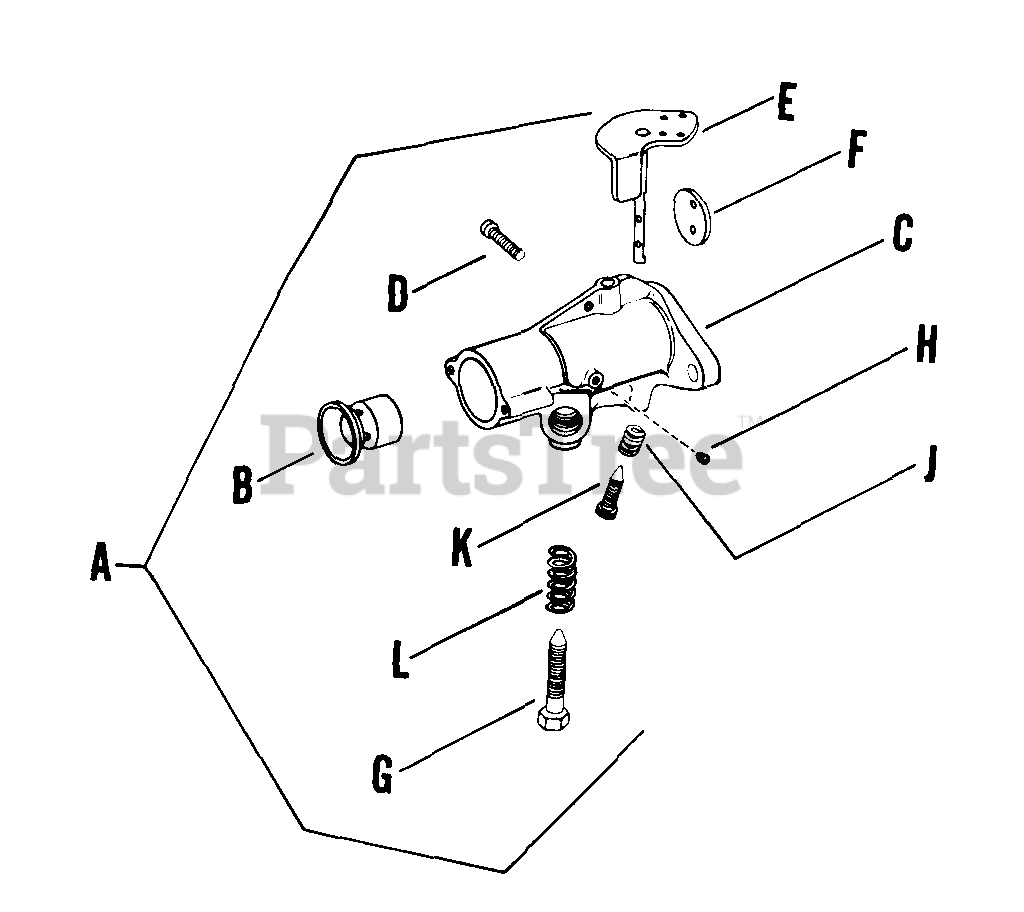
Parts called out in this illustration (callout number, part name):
A	CARBURETOR - USE 46 053 04
B	Venturi
C	Body
D	SCREW - DISCONTINUED
J	SPRING - DISCONTINUED
K	SCREW - DISCONTINUED
